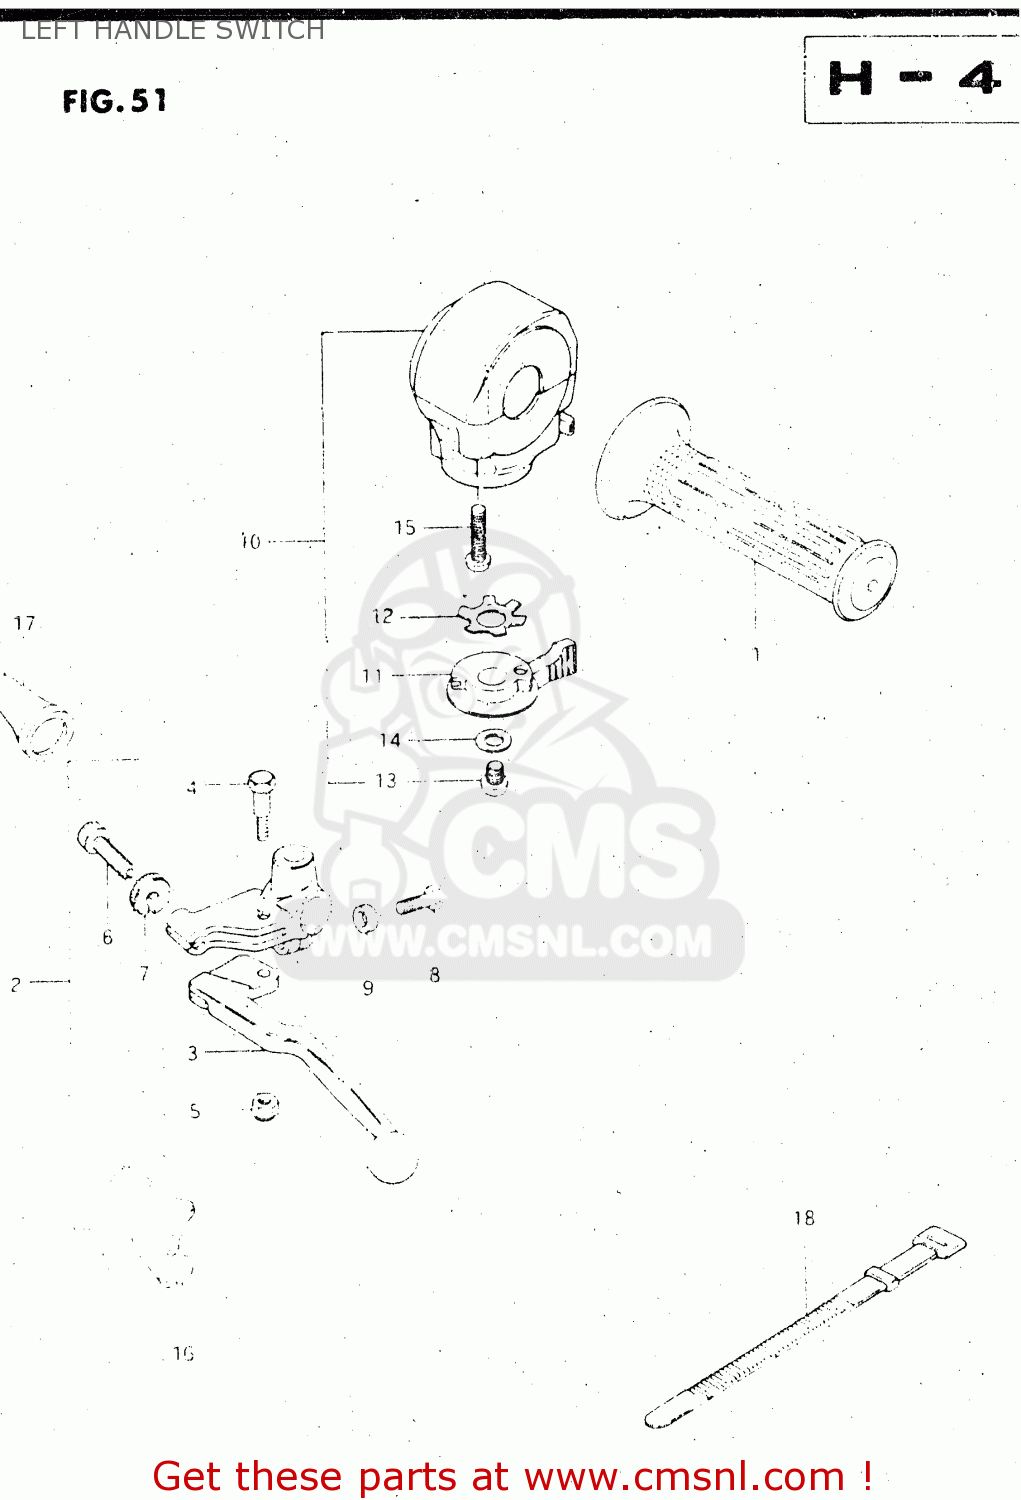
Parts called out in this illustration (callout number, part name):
1	GRIP,LEFT
2	LEVER ASSEMBLY
3	LEVER,CLUTCH
4	BOLT,LEVER
5	NUT 6MM
6	ADJUSTER,CABLE
7	NUT,CABLE ADJUSTER
8	BOLT
9	WASHER
10	SWITCH ASSY, HANDLE LH
11	LEVER,STARTER
12	WASHER
13	SCREW
14	WASHER 6MM
15	SCREW
16	COVER,CLUTCH LEVER
17	BOOT,CLUTCH CABLE
18	CLAMP(L:120)
